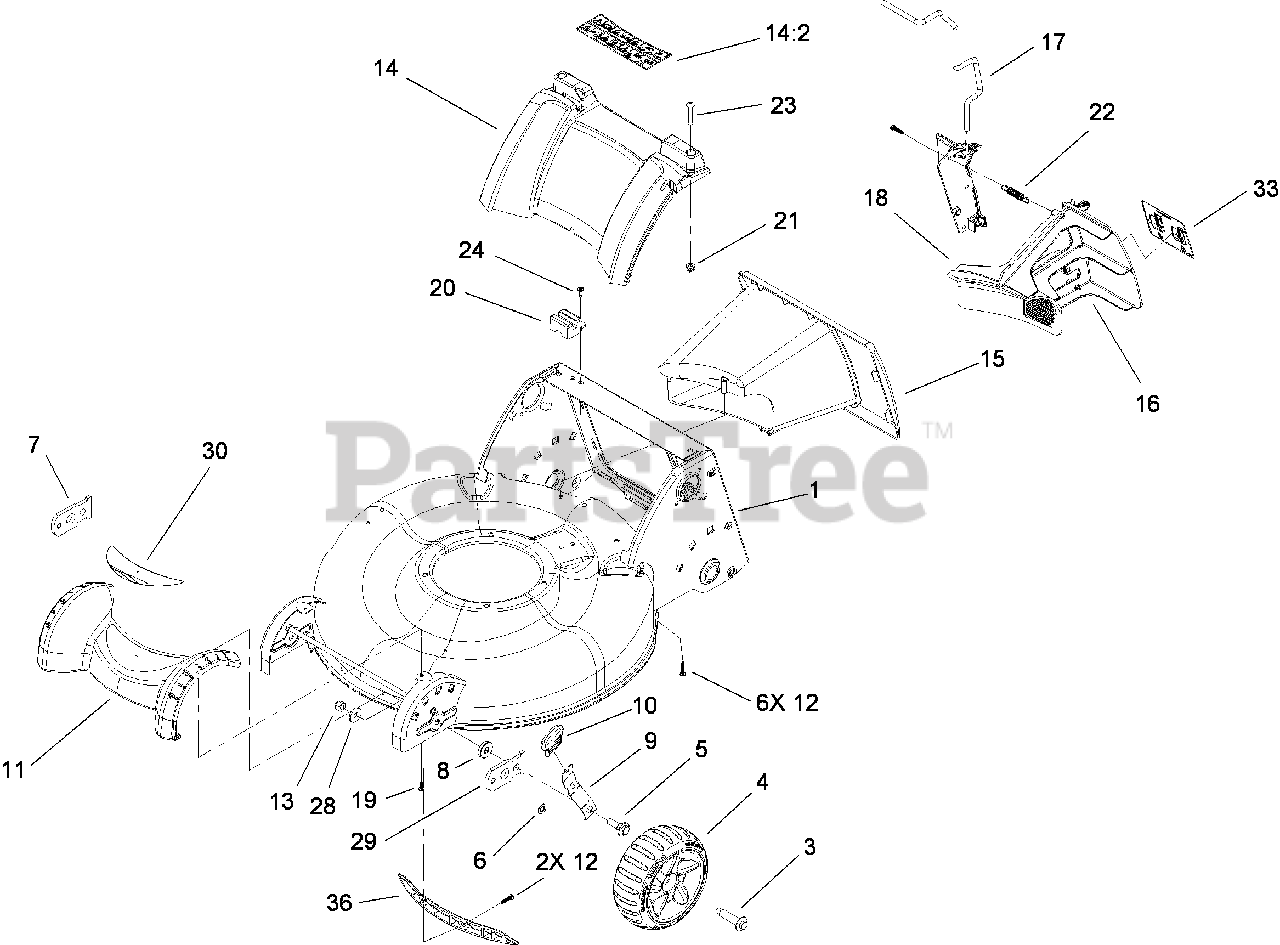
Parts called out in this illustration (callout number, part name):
1	HOUSING ASM
3	BOLT-SHOULDER
4	7 INCH FRONT WHEEL ASM
5	BOLT-SHOULDER
7	ARM-PIVOT, RH
9	ARM-SPRING
11	COVER-FRONT
12	SCREW-PLASTITE
13	NUT-LOCK, NI
14	COVER-REAR
14:2	DECAL-WARNING
16	PLUG-MULCH, LH
17	LATCH-MULCH PLUG
18	PLUG-MULCH, RH
19	SCREW-PLASTITE
20	MODULE-SWITCH
21	NUT-CLIP
22	SPRING-EXTENSION
23	SCREW-PTH
24	SCREW-THREAD FORMING
28	WASHER-HARDENED
29	ARM-PIVOT, LH
33	DECAL-MULCH PLUG
36	INSERT-HOUSING
